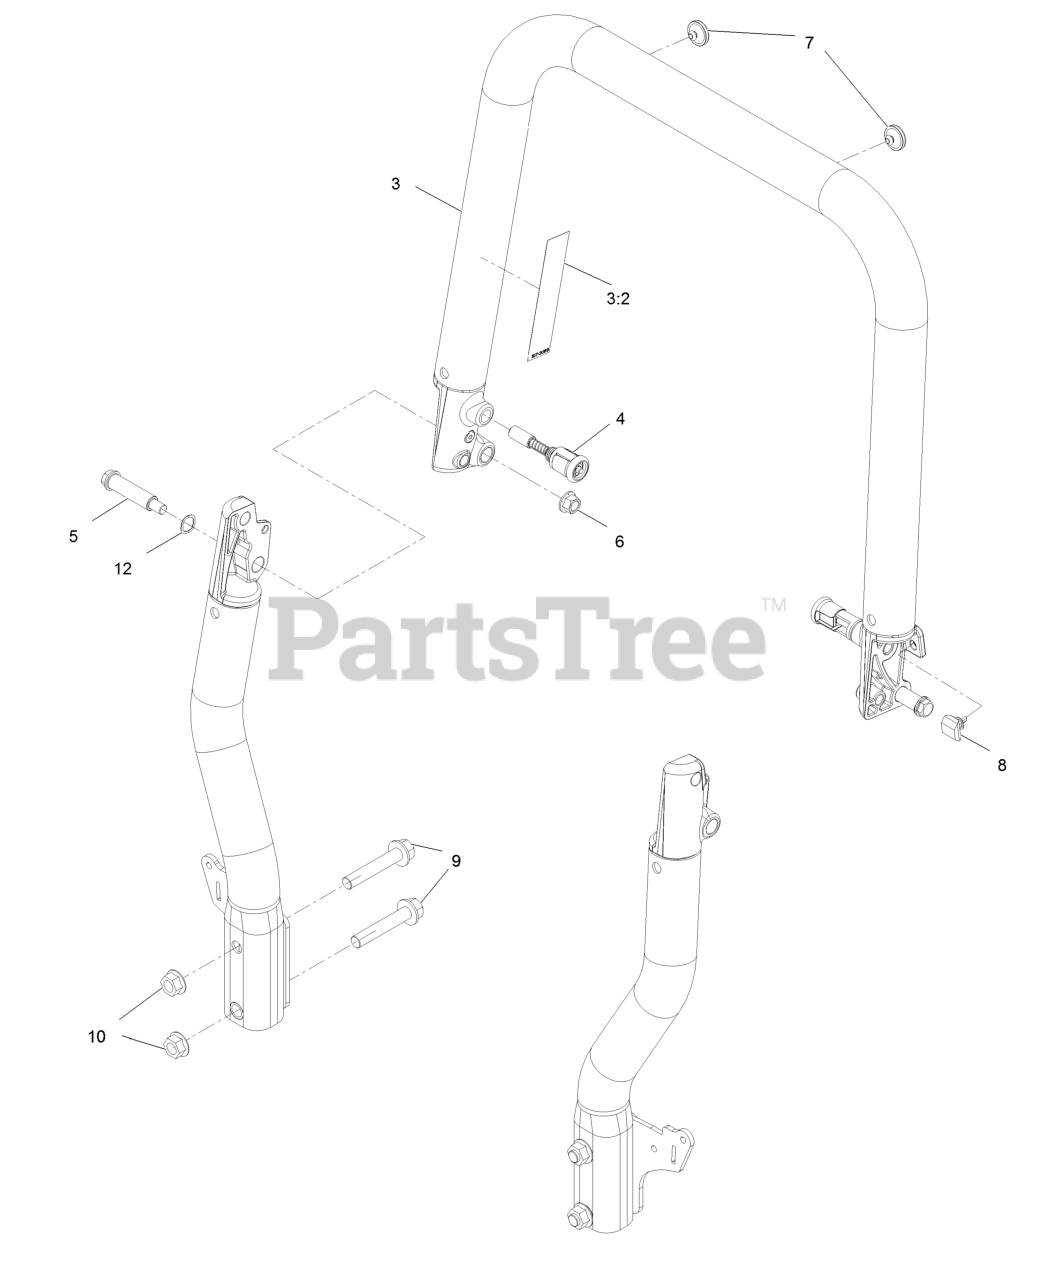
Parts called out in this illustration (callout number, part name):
3	Top Tube ASM
3:2	Decal-Warning
4	Pin-Spring
5	Bolt-Shoulder
6	Nut-Lock
7	Bumper-ROPS
8	Bumper-ROPS
9	Screw-HHF
10	Nut-Flange
12	Washer-Wave
